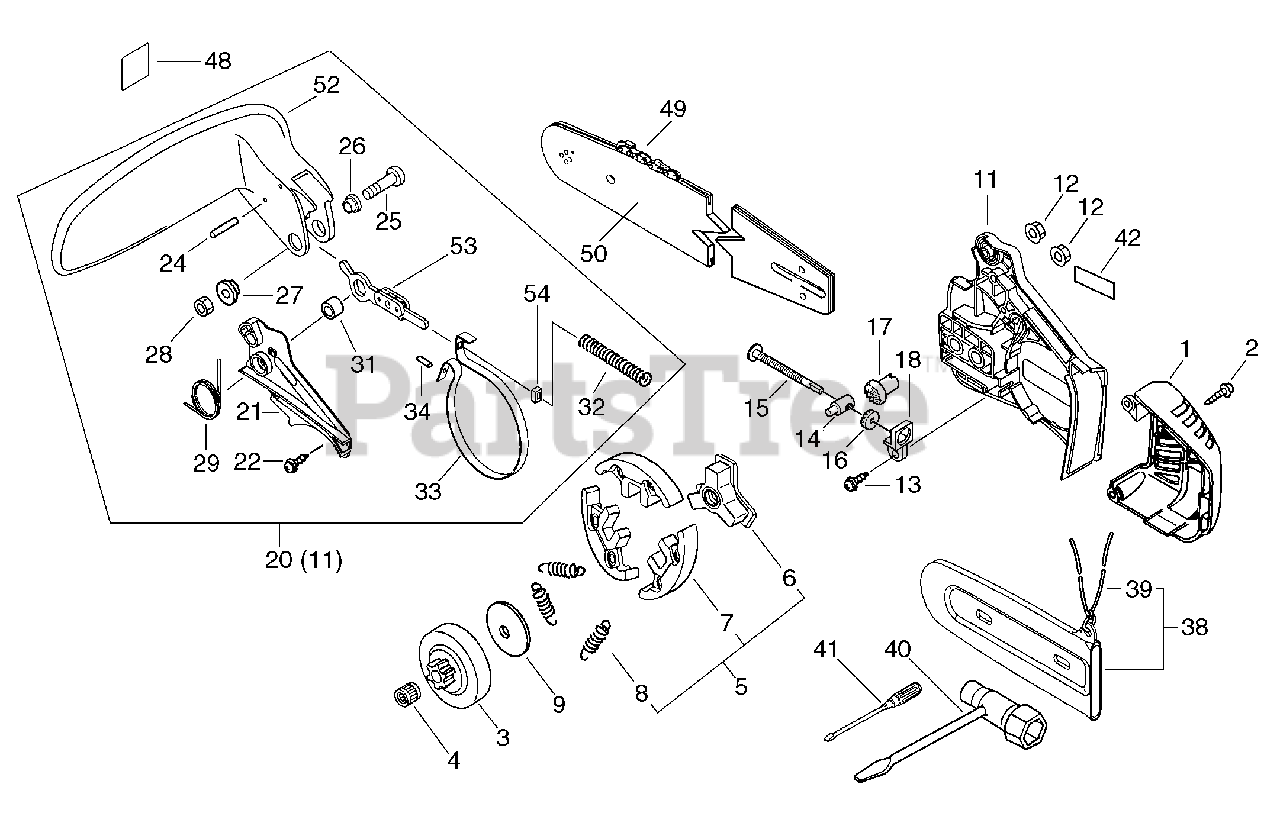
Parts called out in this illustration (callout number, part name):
1	COVER, EXHAUST
2	SCREW - 4X16
3	DRUM, CLUTCH
4	BEARING, NEEDLE
5	CLUTCH ASSY
6	HUB, CLUTCH
7	CLUTCH SHOE SET
8	SPRING,TENSION
9	PLATE, CLUTCH
11	GUARD, SPROCKET
12	NUT - 6 -- FLANGE
13	SCREW - 4X12 -- TAPPING
14	TENSIONER, CHAIN
15	SCREW, TENSIONER
16	GEAR - BEVEL
17	GEAR - PINION
18	COLLAR - 8
20	CHAIN BRAKE ASSY
21	COVER, BRAKE
22	SCREW - 4X12 -- TAPPING
24	PIN - 3X26
25	SCREW - 5X32
27	COLLAR - 5
28	LOCKNUT 5
31	SPACER - 8
33	BAND, BRAKE
38	GUIDE BAR COVER ASSY
40	T-WRENCH
41	SCREWDRIVER
42	LABEL - ECHO
48	LABEL - CAUTION
52	LEVER, BRAKE
53	CONNECTOR, BRAKE
